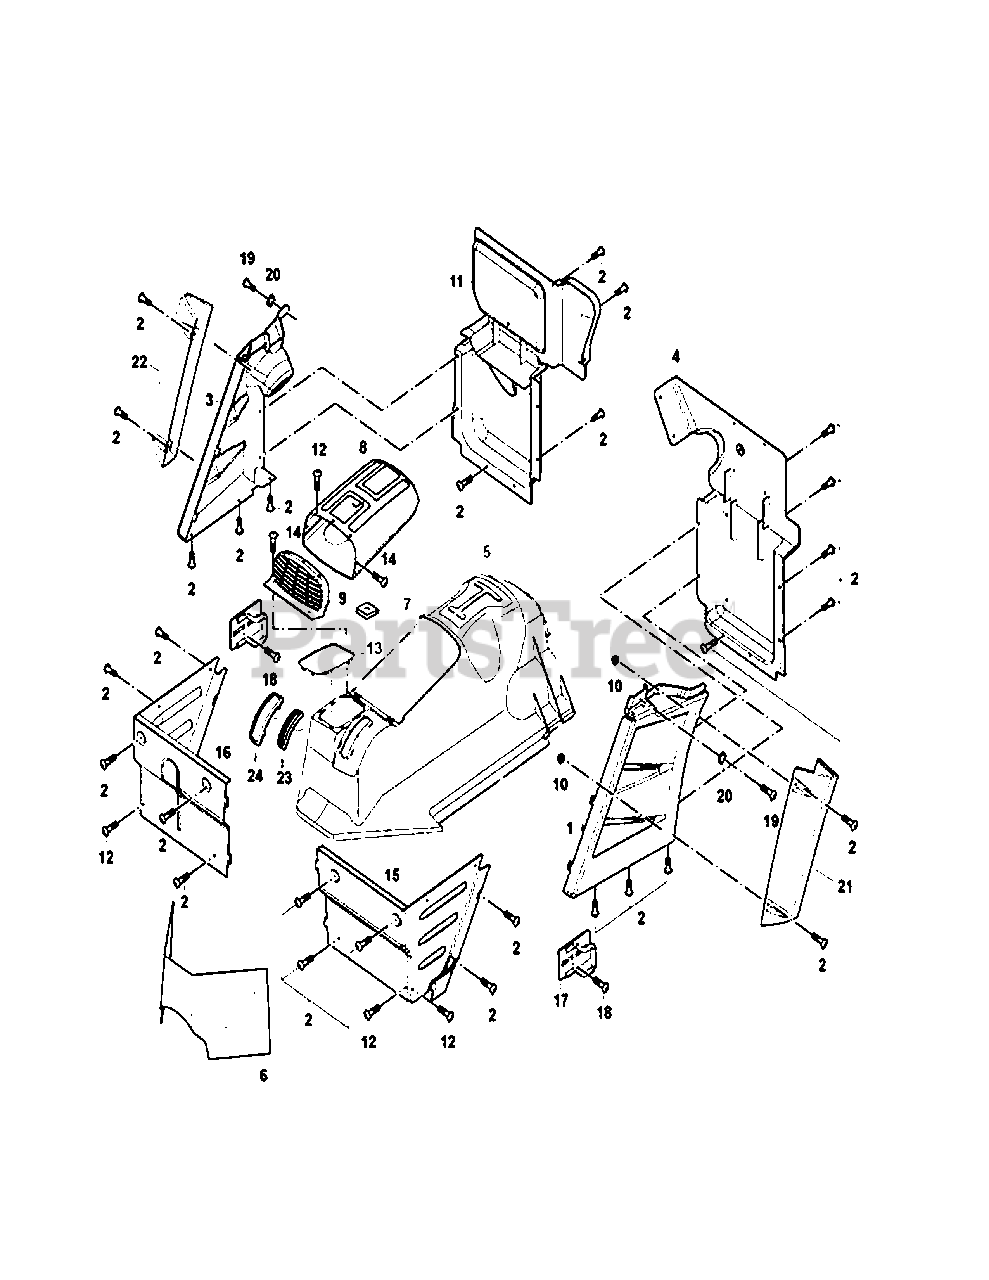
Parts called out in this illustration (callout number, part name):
1	Left Seat Board
2	Cross large plate head screw M6×16
3	Right Seat Board
4	Rear Left Board, Seat
5	Engine Cover Board
6	Insulation Paper VI
7	Screw Thread Clip M5
8	Primary Air Filter Box
9	Primary Air Filter Cap
10	Hexagon Flange Self-Lock Nuts M6
11	Rear Right Board, Seat
12	Expansion Bolt (Plastic)
13	Gear Shift Decoration Cover
14	Cross Large Plate Head Screw M5×16
15	Front Left Board, Seat
16	Front Right Board, Seat
17	Door Locker
18	Hexagon Flange Bolt M6×16
19	Cross Large Plate Head Screw M6×12
20	Nut Clip M6
21	Left side board decorative plate, carrier II
22	Right side board decorative plate, carrier II
23	Dust P. Cover
24	Parking Decoration Cover
